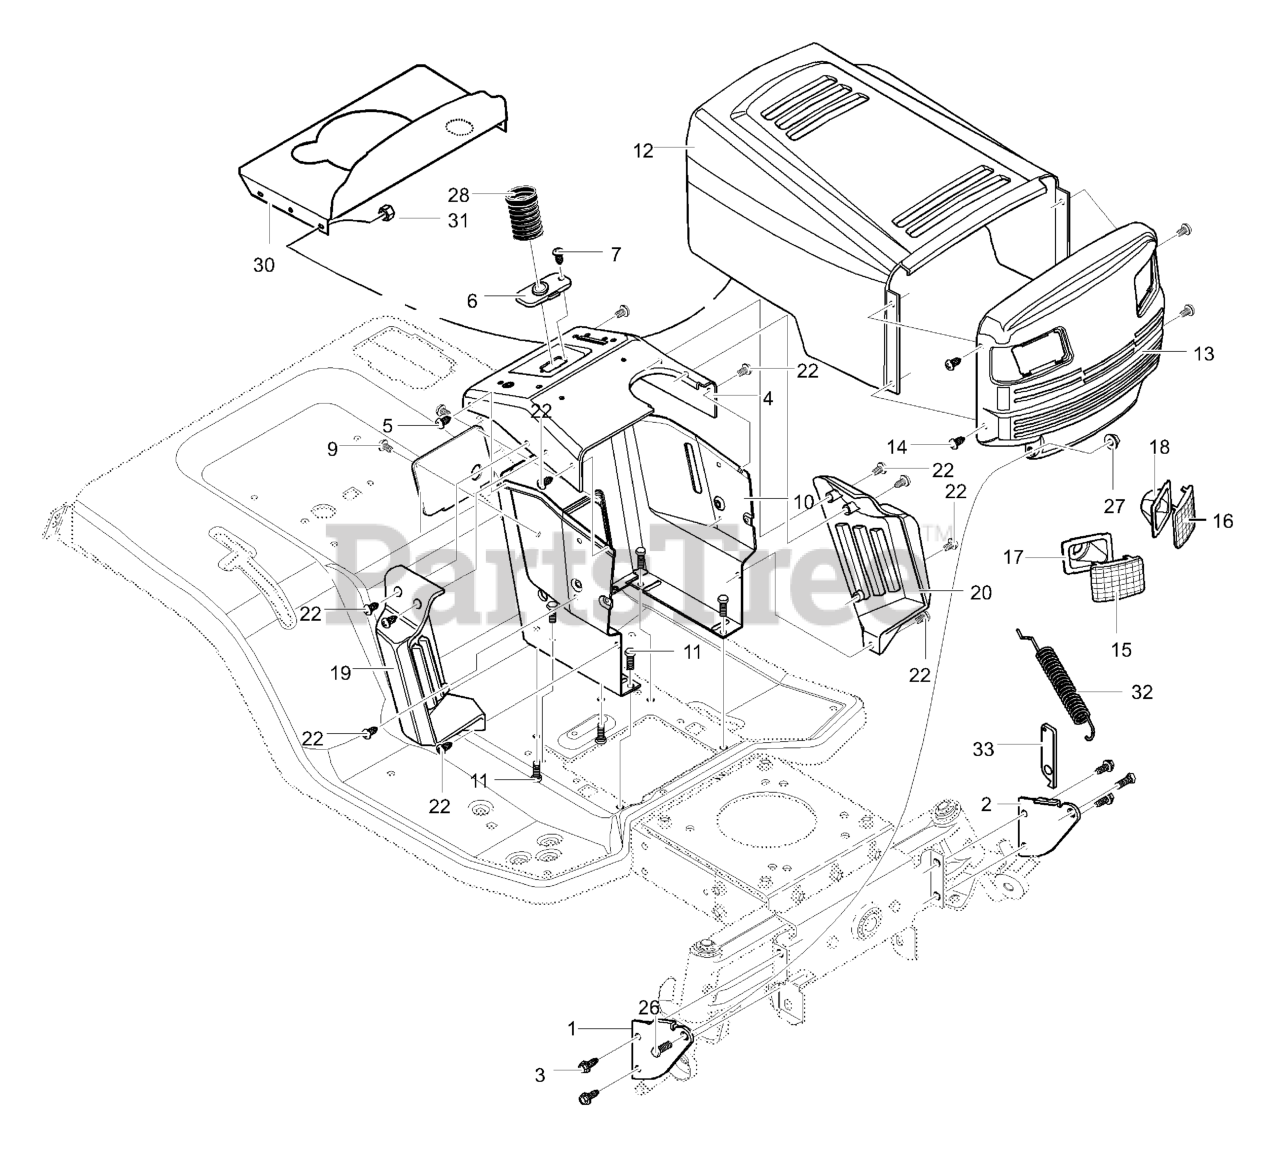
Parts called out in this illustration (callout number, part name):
1	SUPPORT, GRILLE RH
2	SUPPORT, GRILLE LH
3	SCREW, 5/16-18 x .75 HHWATAPSGIBP
5	SCREW, 10-24X.500TRSEG
6	STEERING BRACKET
7	SCREW, 1/4-20X.50WAHHTAP
8	PANEL, ACCESS W/BUZZER
9	SCREW, 10-24X.500TRSEG
10	DASH SUPPORT
11	SCREW, 5/16-18 x .75 HHWATAPSGIBP
14	SCREW, 10-24X.500TRSEG
15	LENS, TWIN RH
16	LENS, TWIN LH
17	REFLECTOR, RH
18	REFLECTOR, LH
19	PANEL, SIDE RH
20	PANEL, SIDE LH
22	SCREW, 10-24X.500TRSEG
26	BOLT, SHOULDER .375
27	NUT, 3/8-16 HWDFLLK MACK
28	BELLOWS-STEERING POST
29	PAD, ADHESIVE
31	NUT, 1/4-20 HEXNYL
32	SPRING, EXT. 5.13LG
33	BRACKET, HOOD
